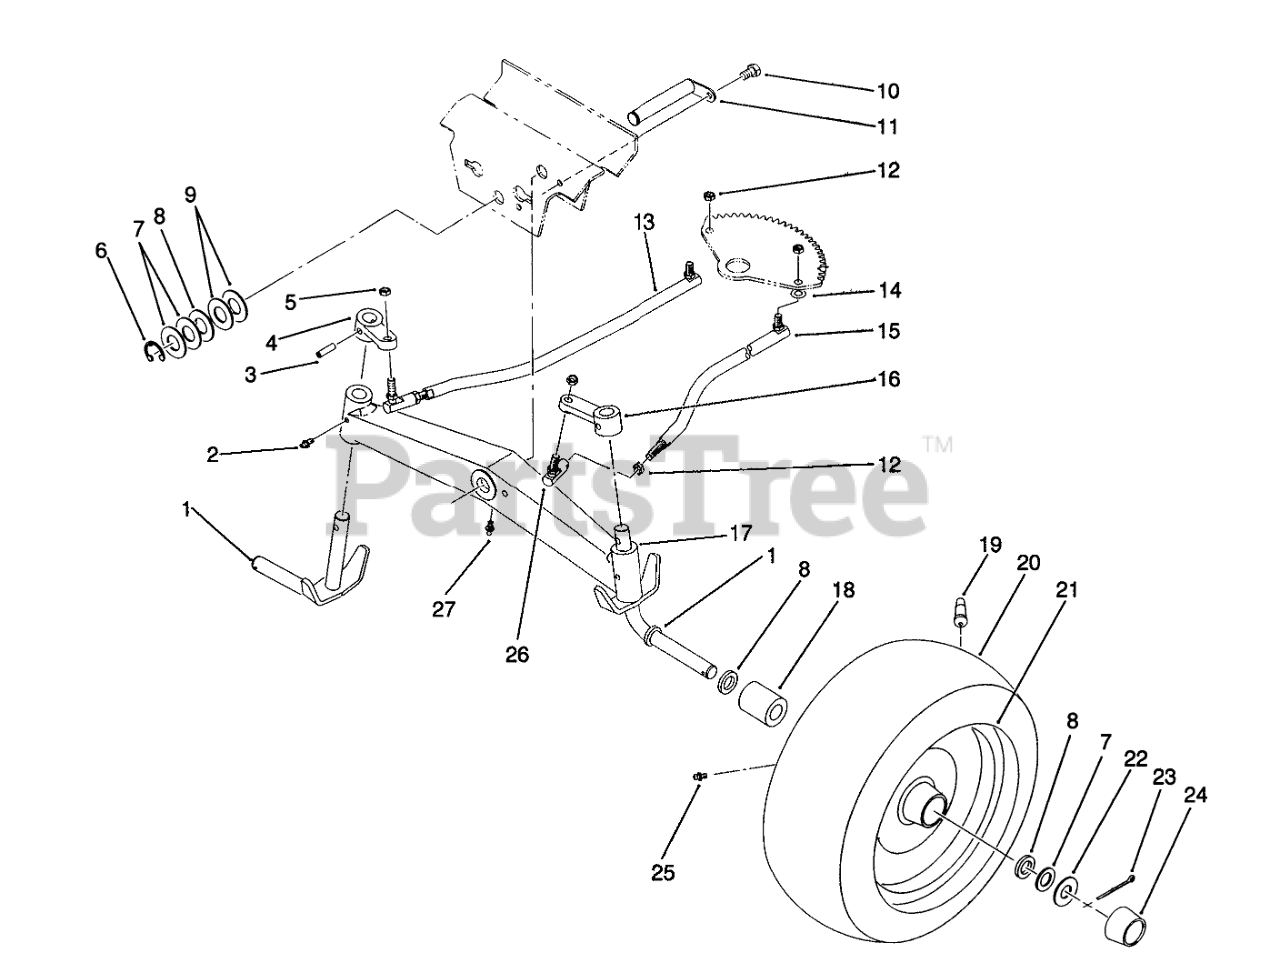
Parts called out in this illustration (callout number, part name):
1	Spindle-W.A.
2	Fitting-Grease
4	Arm-Spindle, R.H.
5	Nut
6	E-RING
7	WASHER-SHIM
8	WASHER
9	Washer
10	SCREW-HWH, TAPTITE
11	WLDMT-AXLE PIN R
13	Ball Link ASM
14	Washer
15	Ball Link ASM
16	Arm-Spindle, L.H.
17	Axle-Front
18	BEARING-WHEEL
19	VALVE
20	Tire (16 x 6.5-8) 2-Ply -2 Wheel Axel
21	Wheel
22	WASHER WHEEL
23	Pin-Cotter
24	HUBCAP
25	ZERK-GREASE
26	BALL-JOINT
27	FITTING-GREASE
